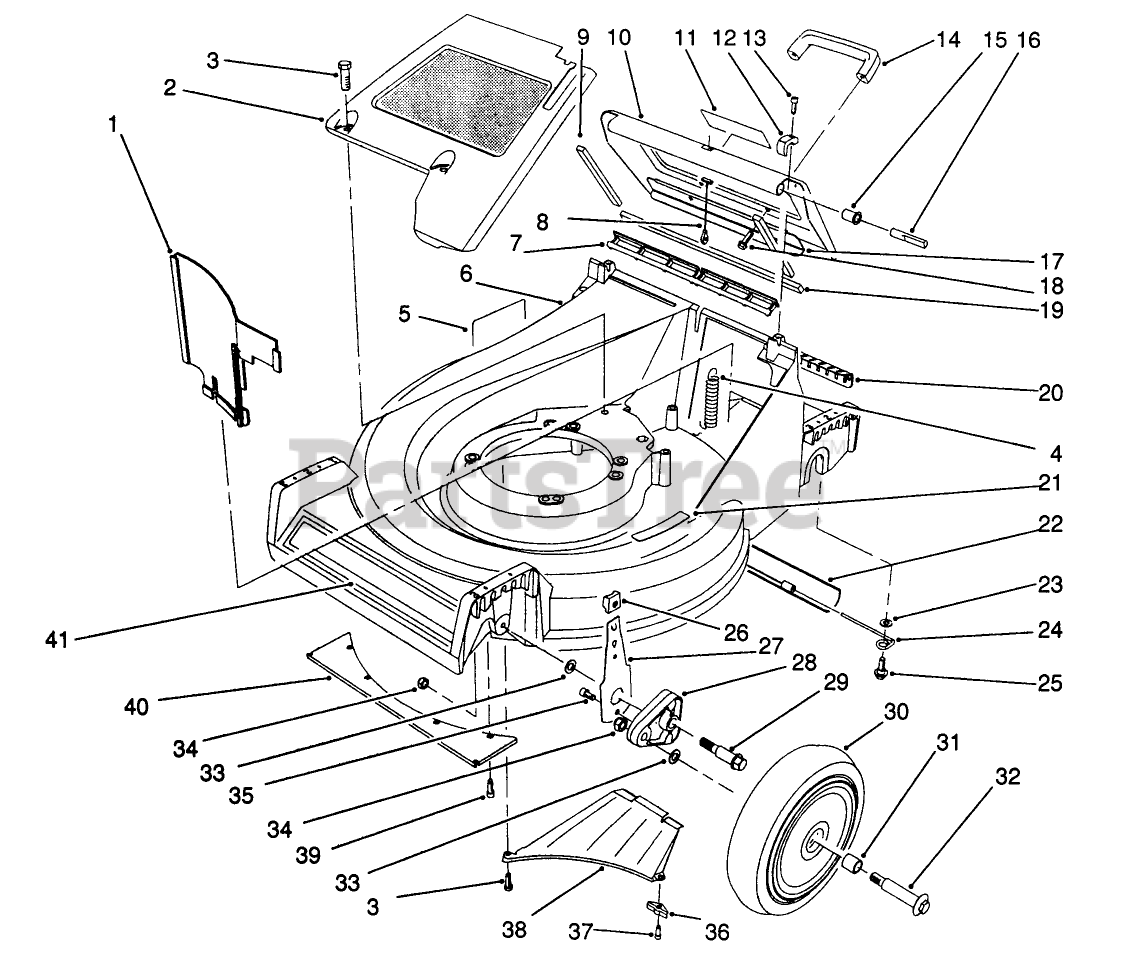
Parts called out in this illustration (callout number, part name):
1	PANEL-VERTICAL
3	SCREW-HWHTF
4	SPRING-EXTENSION
8	DOOR CABLE
13	SCREW-HSH
14	HANDLE-DOOR
15	DOOR BUSHING
18	SCREW-HWH
19	DOOR END SEAL
20	ACCESS COVER
21	DECAL - STEP PAD INT'L
22	TRAILING SHIELD
23	WASHER-PLAIN
24	SHIELD HANGER
25	SCREW-SHOULDER
26	KNOB-ARM
27	FRONT SPRING ARM ASM
28	ARM-PIVOT, FRONT
31	BUSHING
32	WHEEL BOLT
33	WASHER
34	NUT-LOCK
35	SCREW-HSH, THREAD FORMING
37	SCREW-HWHTF
39	SCREW-HWH
